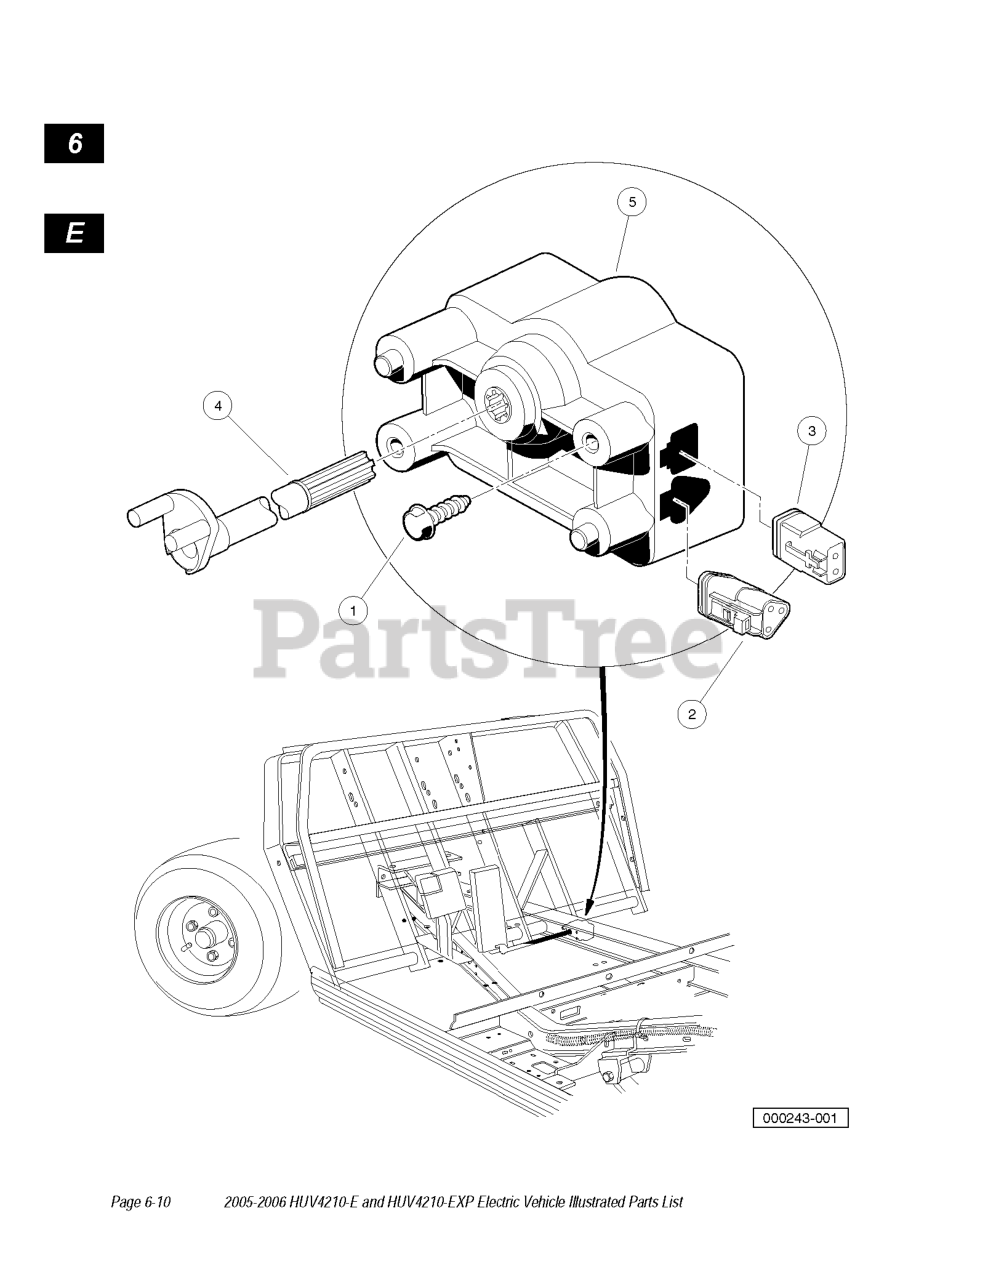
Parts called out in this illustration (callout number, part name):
1	SCREW, #12-16 X .625 HI-LO
2	KIT, 3 PIN PLUG & WEDGE LOCK
3	KIT 2-PIN PLUCG AND WEDGE LOCK
4	BAR DRIVE CAST
